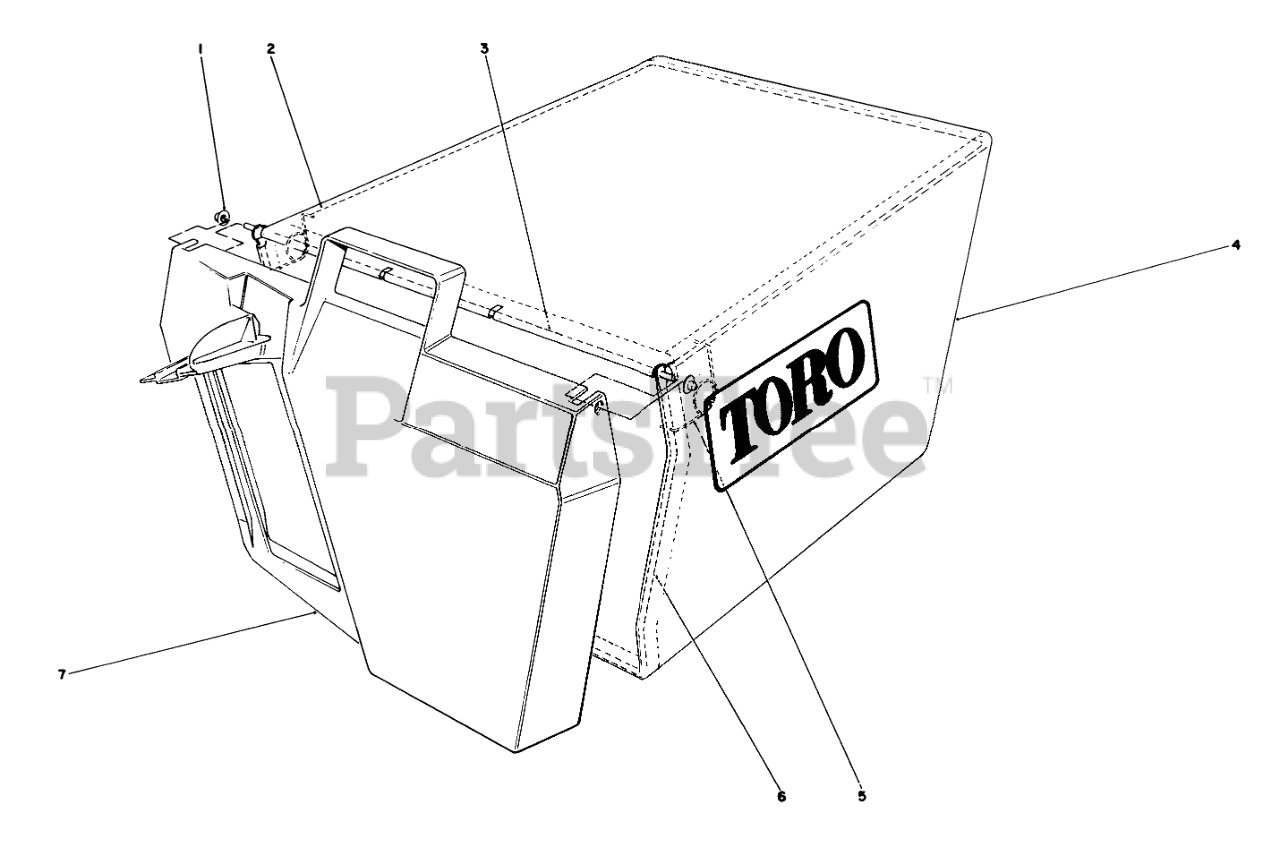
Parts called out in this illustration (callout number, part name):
1	NUT-PUSH
2	FRAME-BAG, UPPER
3	HINGE-DOOR, BAG
4	BAG-GRASS
5	SPRING
6	FRAME-BAG
7	DOOR-BAG
